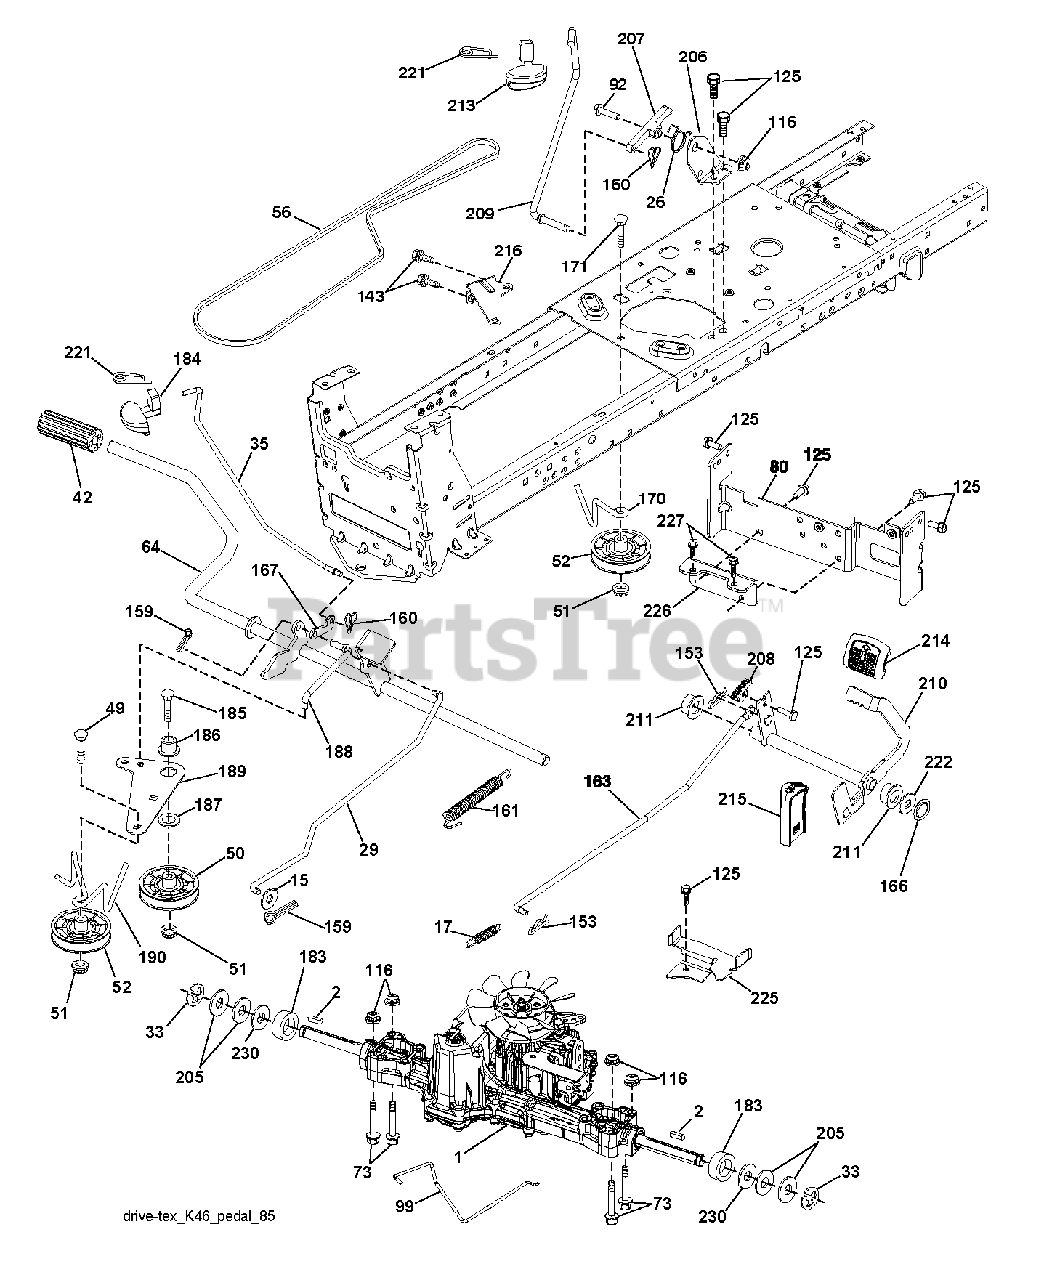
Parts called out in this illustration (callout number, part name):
2	SQUARE KEY
15	WASHER
17	SPRING.BRAKE.K46.GREEN
26	SPRING.RETURN.CRUISE
29	ROD.BRAKE.K46
35	ROD.BRAKE.PARTK.HUSQ.TEX
42	PEDAL COVER T
50	IDLER.FLAT.910.OFFSET
51	NUT LOCK FLG 3/8-16 UNC
52	IDLER.V-GROOVE.910.OFFSET
56	V-BELT.MOWER.92.40.42/K46
64	SHAFT.ASM.PEDAL.BRK.CNTR
80	STRAP.TORQUE.K46.K57R.TT
92	BOLT
99	ROD.SPRING.BYPASS.K46.LT.Z
116	NUT LOCK HEX FLANGE 5/16-18
125	SCREW
143	SCREW LT
153	RETAINER M
159	COTTER PIN
160	RETAINER CLIP
161	SPRING, RETURN LT
163	ROD.CONTROL.PEDAL.K46
166	NUT.PUSH.625
167	LATCH.BRAKE.SPRING
170	KEEPER.V-IDLER.CENTER.
183	SPACER AXLE
184	RB HANDLE.PARKG.BRK.HUS/PRED
186	SPACER.RETAINER
187	WASHER 12/32X2X10GA
188	RP LINK.CLUTCH.GROUND.DRIVE
189	BELLCRANK.GROUND.DRIVE.TEX.
190	KEEPER.BELLCRANK.DRIVE
206	BRKT.MOUNT.LATCH.CRUIS
207	LATCH.CONTROL.CRUISE
208	GEAR.SECTOR.CONTROL.CR
209	ROD.CONTROL.CRUISE.GT.
210	ROCKER.ASM.PEDAL.CONTR
211	BEARING.NYLON
213	KNOB.CONTROL.CRUSIE.HU
214	PEDAL.FORWARD.PAD.TEX
215	PEDAL.REVERSE.TEX.GT.4
216	BRACKET.PULLEY.IDLER.W/TEX
221	RETAINER.SPRING.CLIP.H
222	WASHER 21/32 X 1-1/4 X 10 GA.
225	KEEPER.BELT.TRANSAXLE.K46
226	BRACKET.MOUNT.TORQUE.K46.TLT
227	SCREW
230	WASHER.HARDENED
